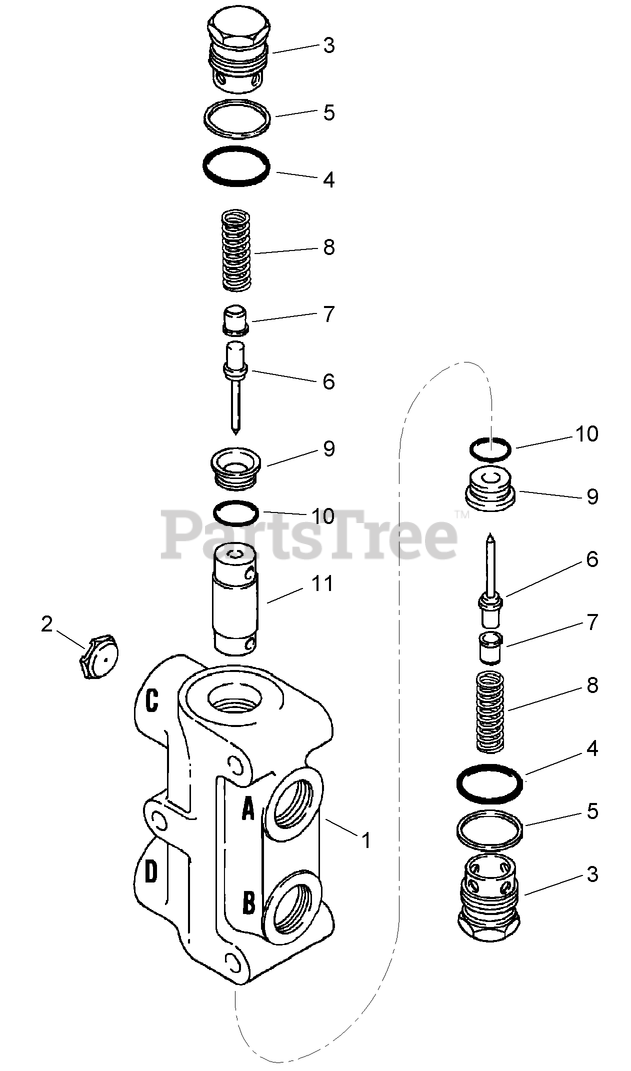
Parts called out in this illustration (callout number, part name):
1	HOUSING
2	PLATE-ORIFICE
3	PLUG - Lockout Valve
4	O-RING
6	POPPET
7	EYELET-POPPET
9	SEAT - Poppet
11	PLUNGER
